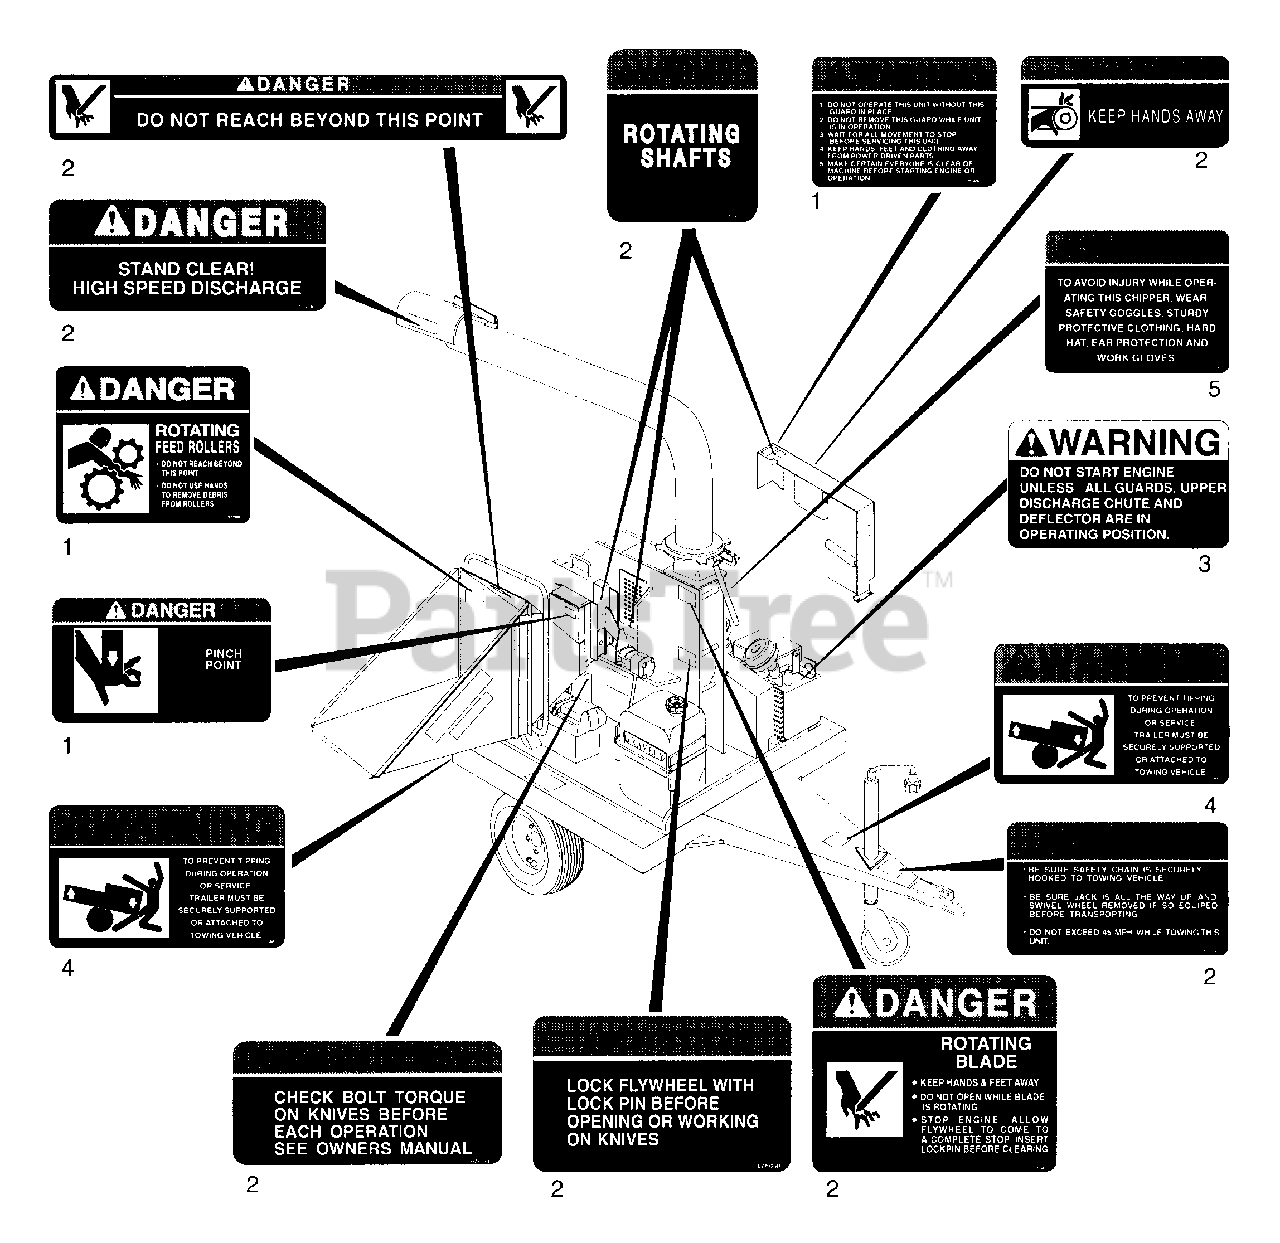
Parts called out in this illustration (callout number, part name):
1	Decal Set
2	Decal Set-Large Chipper
3	Decal, Warning Engine Start
4	Decal, Tipping
5	Decal, Warning-Protective
